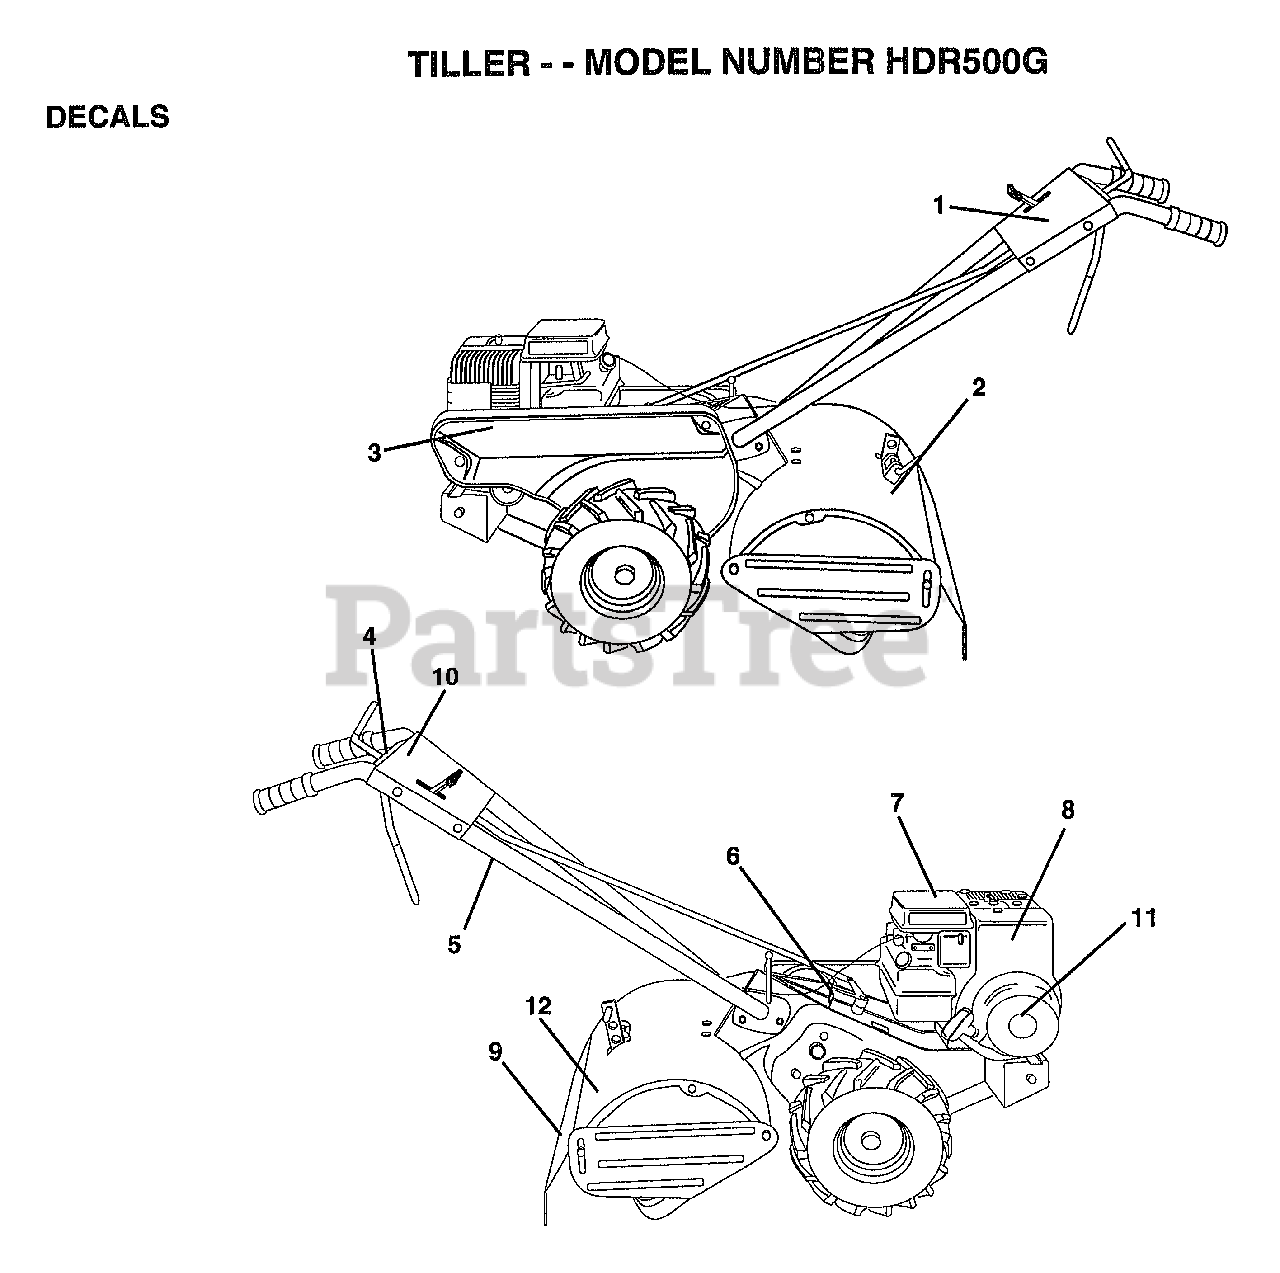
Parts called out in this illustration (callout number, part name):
1	"DECAL PANEL,CTRL"
2	"DECAL SHIELD,TINE"
3	"DECAL GUARD, BELT"
4	DECAL.CONTROL
5	DECAL.HAND.PLACE
6	DECAL CRT
7	DECAL.CAUTION.E/S
8	DECAL, BRIGGS & STRATTON
9	DECAL.WARN.ROT.TI
10	DECAL REVERSE
12	DECAL.TINE.SHIELD
